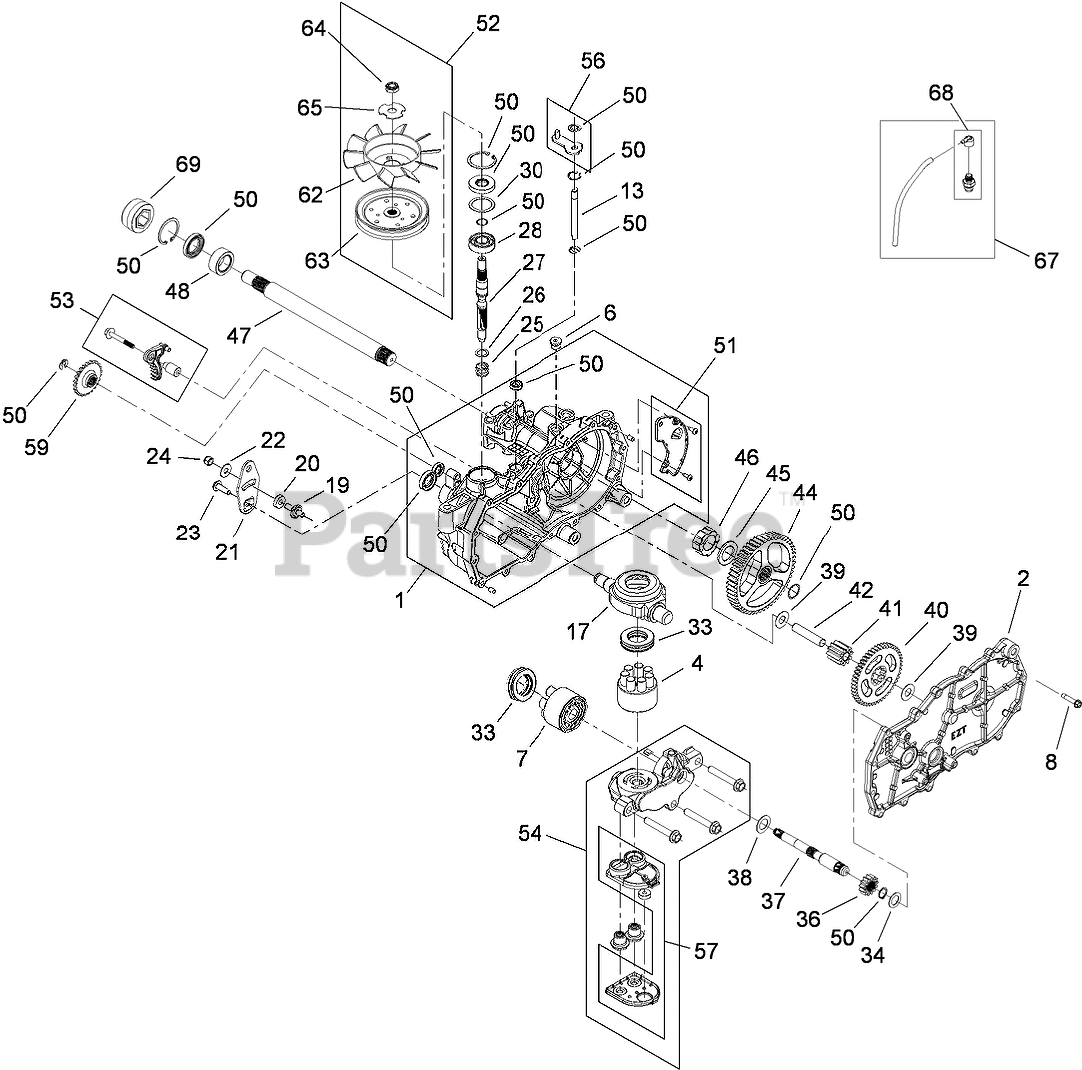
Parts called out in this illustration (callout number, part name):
1	RH MAIN HOUSING ASM
2	RH SIDE ASM
4	PUMP BLOCK ASM
6	PLUG-THREAD, STRAIGHT
7	CYLINDER BLOCK KIT
8	SCREW-HHF
13	ROD-BYPASS
17	SWASHPLATE-TRUNNION
20	PUCK-FRICTION
21	ARM-CONTROL
22	WASHER-PIVOT
25	SPRING-BLOCK
26	WASHER-THRUST
27	SHAFT-INPUT
28	BEARING-BALL
30	SPACER
33	BEARING-THRUST
34	WASHER-FLAT
36	GEAR-PINNION, 13T
37	SHAFT-MOTOR
38	WASHER
39	WASHER
40	GEAR-10T/48T
41	GEAR-JACKSHAFT, 10T
42	PIN-JACKSHAFT
44	GEAR-52T, BULL
45	WASHER
46	BEARING-SLEEVE
47	SHAFT-AXLE
48	BUSHING-AXLE
50	SEAL KIT
51	EXPANSION PLATE KIT
52	Fan Pulley Kit
53	BRAKE ARM KIT
54	CENTER SECTION FILTER KIT
56	BYPASS ARM KIT
57	FILTER KIT
59	DISC-BRAKE, COG
62	FAN-6 INCH, 10 BLADE
63	PULLEY
64	NUT-LOCK
65	WASHER-SLOTTED
67	BREATHER KIT
68	BREATHER ASM
69	COVER-NUT, AXLE
